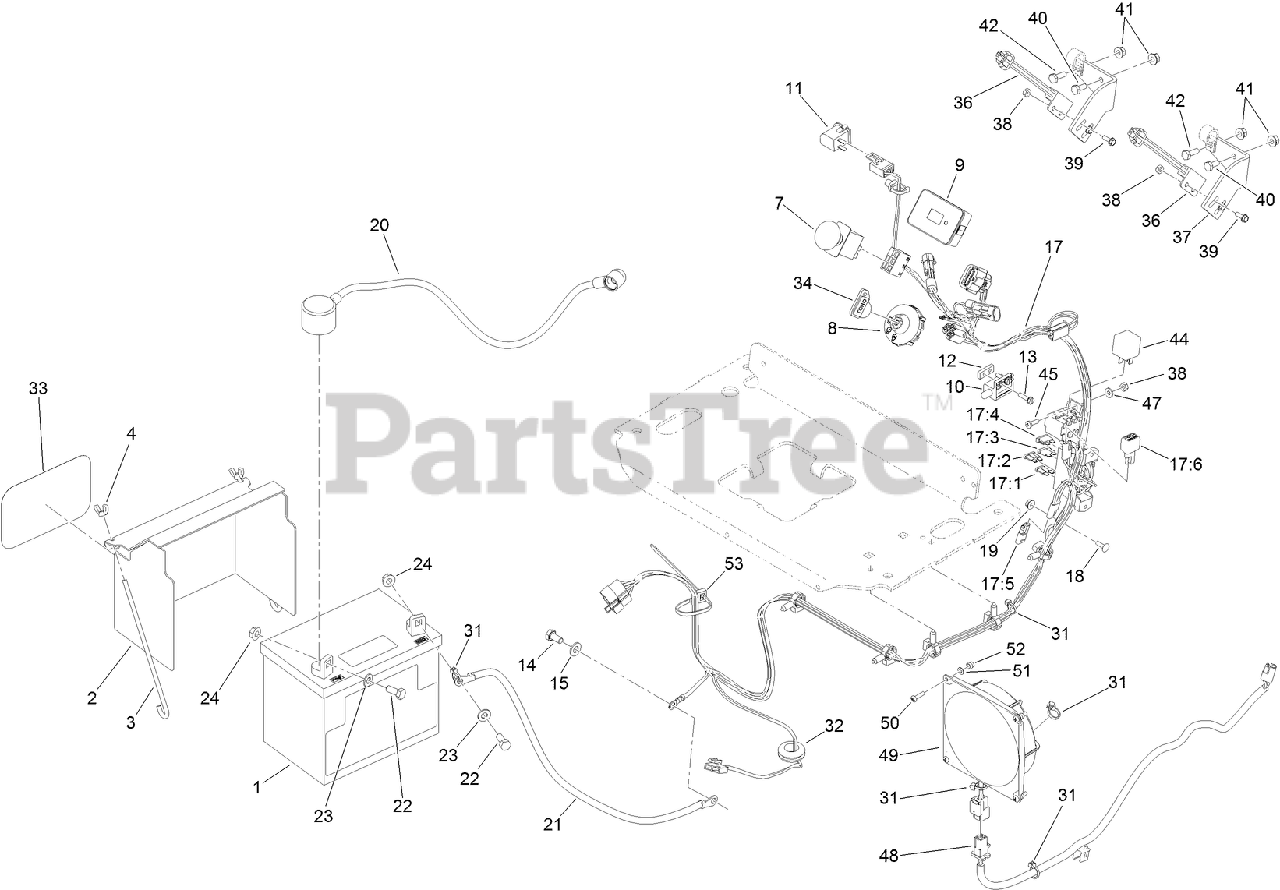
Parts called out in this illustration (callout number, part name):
1	BATTERY-DRY
2	COVER-BATTERY
3	BOLT-HOLDDOWN
4	WINGNUT
7	SWITCH-PTO, ON-ON-(ON)
8	SWITCH-IGNITION
9	MODULE-HOUR METER
10	SWITCH-CLOSED, NORMALLY
11	SWITCH-BAIL
12	PLATE-TAPPED
13	SCREW-HWH
14	SCREW-HH
15	WASHER-PLAIN
17	HARNESS-WIRE
17:1	FUSE-BLADE, 30 AMP
17:2	FUSE-BLADE, 25 AMP
17:3	FUSE-BLADE, 10 AMP
17:4	FUSE-BLADE, 15 AMP
17:5	CAP-PLUG
18	BOLT-CARR
19	NUT-HF
20	CABLE-BATTERY, POSITIVE
21	CABLE-BATTERY, BLACK
22	SCREW-HH
23	WASHER-PLAIN
24	NUT-HHF, SMOOTH
31	TIE-CABLE
32	GROMMET
33	DECAL
34	KEY-IGNITION
36	SWITCH-PROXIMITY
37	BRACKET-MOUNT, SWITCH
38	NUT-LOCK, NI
40	SCREW-HH
41	NUT-HHF
42	SCREW-HH
45	SCREW-PPH
47	WASHER-FLAT
48	HARNESS-WIRE, FAN
49	FAN-ELECTRIC
50	SCREW-PPH
51	WASHER-FLAT
52	NUT-LOCK
53	TIE-CABLE
